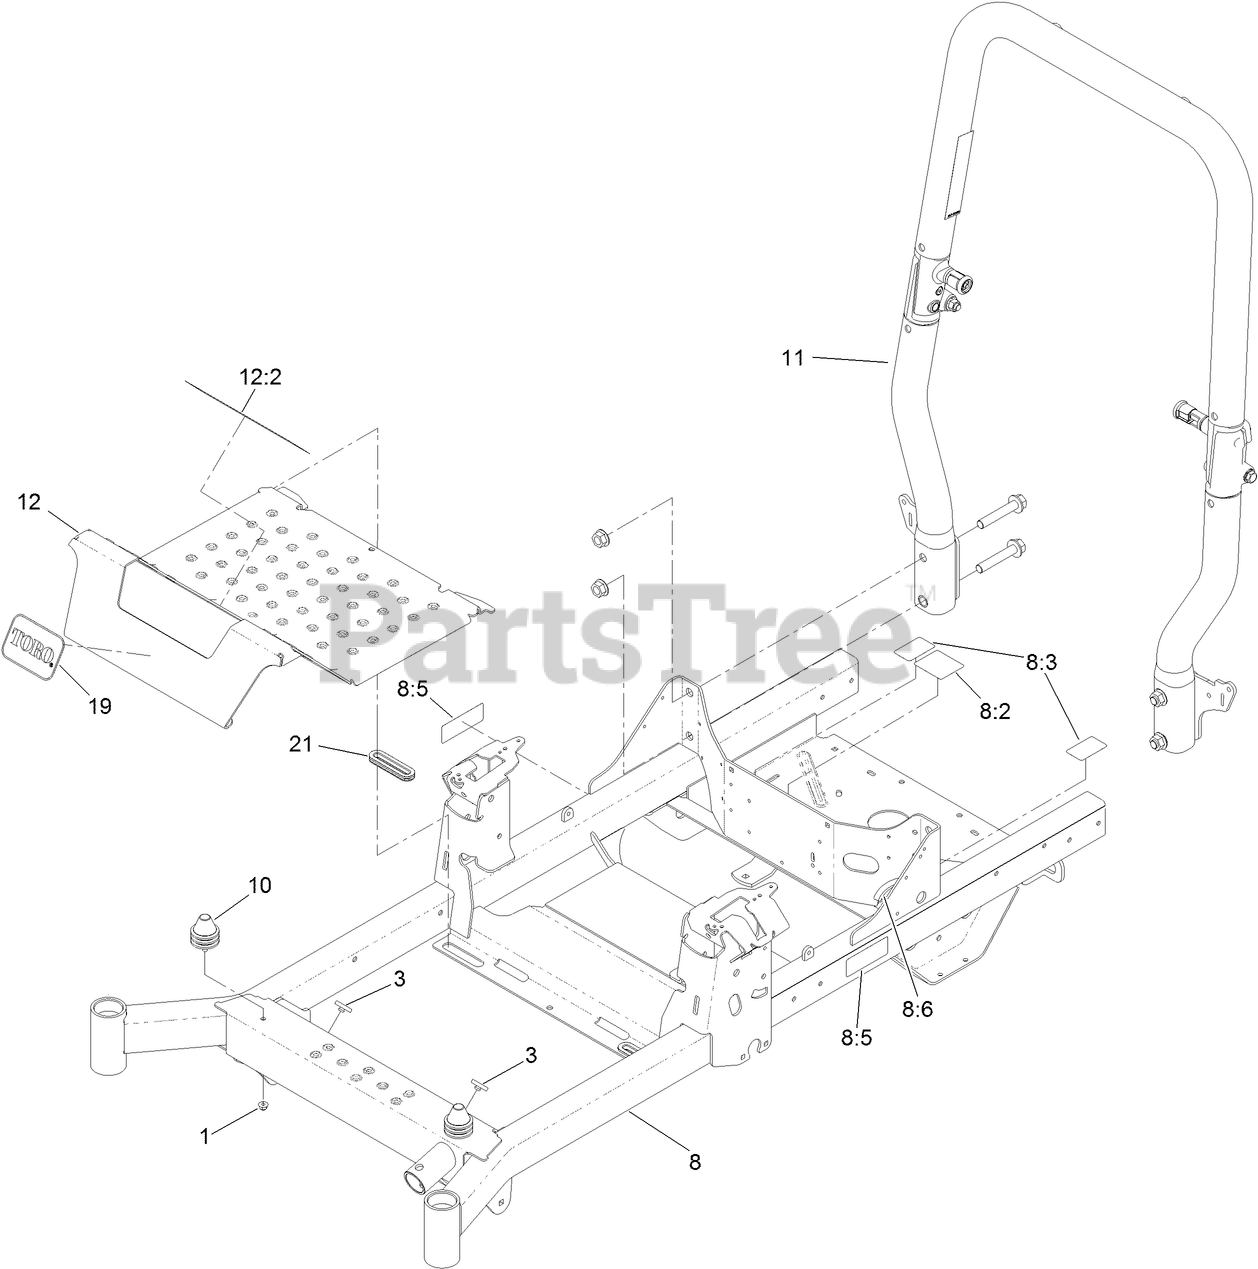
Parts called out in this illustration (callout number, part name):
1	NUT-HF, NI
3	BUMPER-PUSH-IN, RUBBER
8	FRAME ASM
8:2	DECAL-ROUTING, BELT
8:3	DECAL-RELEASE, DRIVE
8:5	DECAL-WARNING
8:6	STRIP-SEAL
10	ISOLATOR
11	ROPS ASM
12	PAN-FLOOR
12:2	DECAL-DANGER
19	DECAL
21	GROMMET-RUBBER
